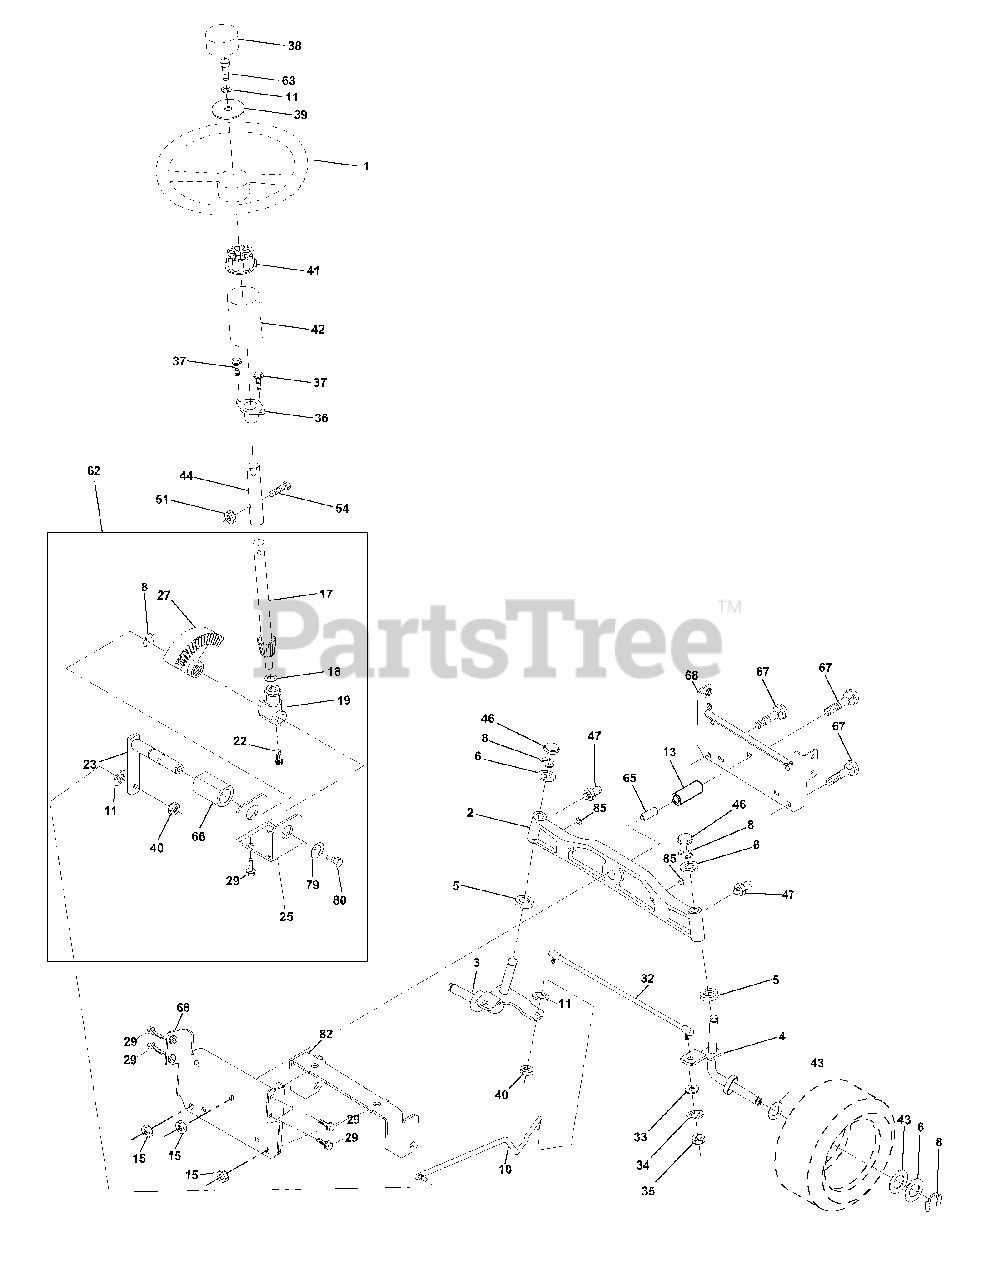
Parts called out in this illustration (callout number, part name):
1	Wheel Steering
2	Axle Asm Stmp Dropped STLT
3	Spindle Asm LH
4	Spindle Asm RH
5	Bearing Race Thrust Harden
6	Washer 25/32 X 1-5/8 X 16 Ga
8	Ring Klip #t5304-75
10	Link Drag
11	Washer Lock Hvy Hlcl Spr 3/8
13	Spacer Brg. Axle Front
15	Nut Hex Flange Lock
17	Shaft Asm Strg
18	Washer Thrust 515x 750x 033
19	Support Shaft
22	Screw Hex Wsh Hd Torx
23	Shaft Asm Pittman
25	Bracket Steering
27	Gear Sector
28	Washer 13/32 x 7/8 x 16 Ga.
29	Screw 3/8-16x.75
32	Rod Tie
33	Washer 11/32 x 3/4 x 16 Ga.
34	Washer Lock Hvy Hlcl Spr 5/16
35	Crownlock Nut 5/16-24
36	Bushing Strg
37	Screw
38	Insert Cap Strg Wh Au
39	Washer 13/32 X 2-3/8 X 12 Ga
40	Lock nut
41	Adaptor Wheel Strg
42	Boot Steering Dash
43	Washer 25/32 X 1 1/4 X 16 Ga
44	Extension Steering Shaft LR/LT
46	Cap Spindle Fr Top Blk
47	Fitting Grease
51	Nut Lock Hex w/Ins 5/16-18
54	Bolt Fin Hex 5/16-18 Unc x 1-1/4
62	Kit, Steering Assembly Svc
63	Bolt Fin Hex 3/8-16unc x 1 Gr. 5
65	Brace Axle
66	Bearing Arm Pittman
67	Bolt Rdhd Sq 3/8-16 Unc x 2-1/4
68	Axle, Brace
79	Washer 13/32 x 1-1/4 x 12 Ga.
80	Bolt Hex Nylon 3/8-16 x 3/4
82	Bracket Susp. Chassis Front
85	Fastener Christmas Tree
